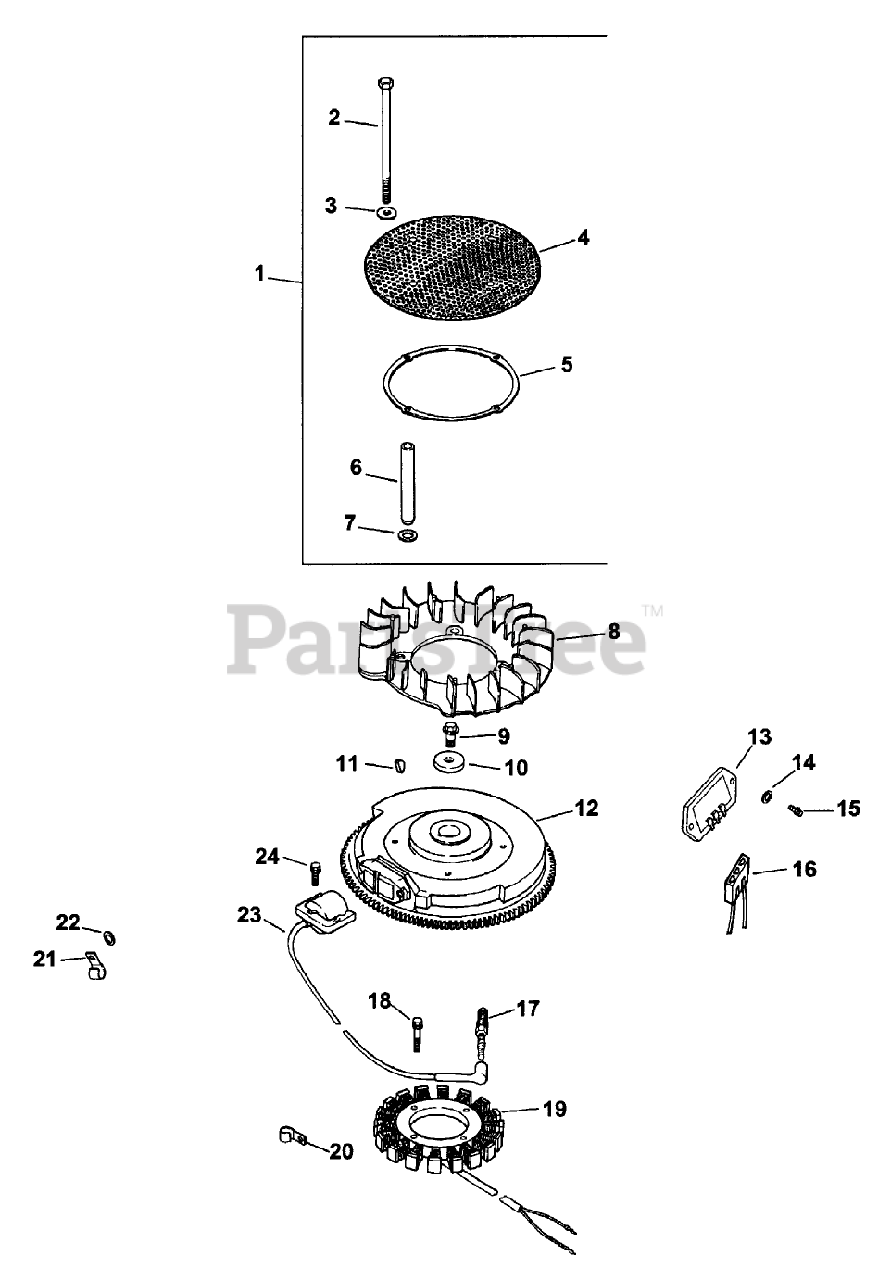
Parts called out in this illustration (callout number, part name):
1	Kit, chopper screen (Includes 2-7)
2	Screw-Hex
3	Washer
4	Screen-Grass
5	Ring-Support
6	Spacer
7	Washer, sping
8	Fan
9	Screw
10	Washer
11	Key
12	Flywheel
13	Rectifier-Regulator
14	Washer
15	Screw
16	Connector
17	Plug-Spark
18	Screw
19	Kit, 15 amp stator (Includes Bracket, stator wire 24 126 71)
20	Clip
21	Clip
22	Washer
23	Module-Ignition
24	Screw
